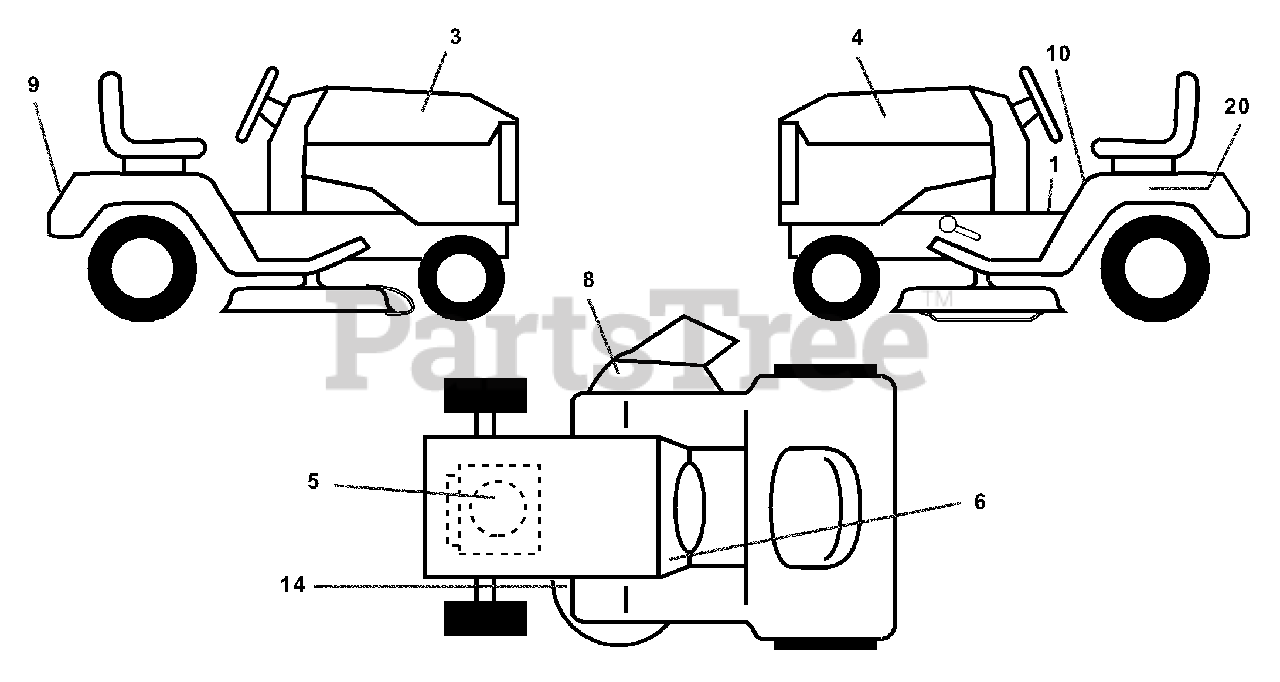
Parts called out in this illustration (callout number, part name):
1	Decal Oper. Step Thru Eng/Fr
3	Decal Hood RH
4	Decal Hood LH
5	Decal HP Engine
6	Decal Dash Logo
8	Decal Warning
9	Decal Fender Husq
10	Decal Fender Danger Eng/Fr
14	Decal V-Belt Schematic
20	Decal Bat Dan/Psn
MK380	Mulcher Kit with Blades
